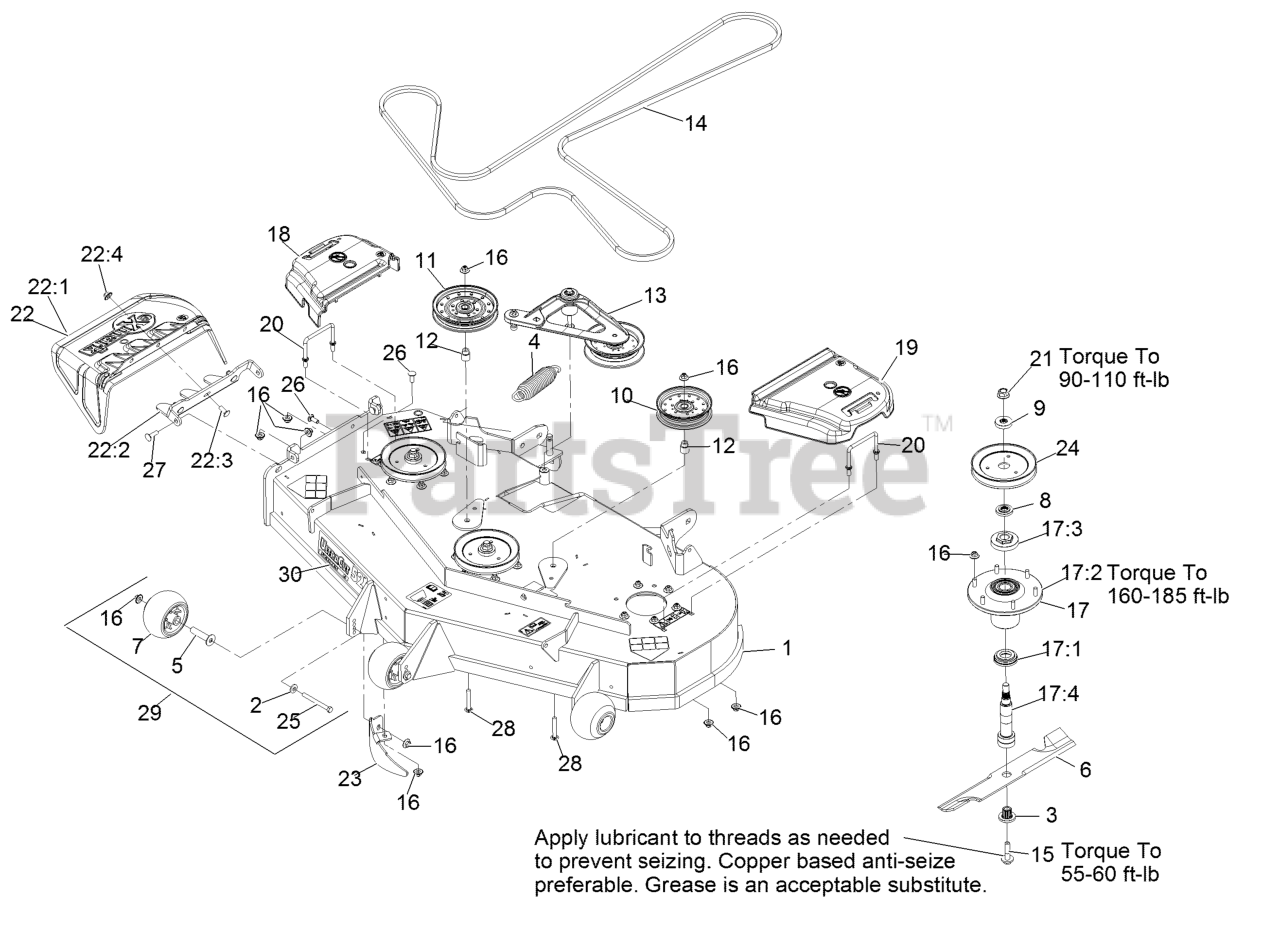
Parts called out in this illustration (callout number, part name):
1	ASM,DECK W/ DECALS 52
2	WASHER-BELLEVILLE
3	BUSHING,SPLINED
4	SPRING-EXTENSION
5	AXLE, ROLLER
7	ROLLER-SCALP, ANTI
8	SPACER,SPLINED STEPPED
9	SPACER,SPLINED
12	BUSHING-IDLER
13	DECK IDLER ASM
14	BELT,V-B X 186.00"
15	SCREW,SEMS 1/2-20 X 2.19
16	Nut-Nyloc 3/8-16 Flg
17	ASM,SPINDLE HOUSING
17:1	GUARD,BOTTOM
17:2	ASM,CUTTER HOUSING
17:3	NUT, SPINDLE 7/8-14
17:4	SPINDLE,DOUBLE SPLINE
18	COVER-BELT, RH
19	COVER-BELT, LH
20	WIREFORM-COVER
21	NUT-FLANGE, CENTERLOCK
22	ASM,DISCHARGE CHUTE
22:1	CHUTE,DISCHARGE
22:2	BRACKET,DISCHARGE CHUTE
22:3	SCREW-CARR
22:4	Nut-Nyloc 3/8-16 Flg
23	BAFFLE-DOGLEG, LZ-VT52
24	SHEAVE,BLADE DRIVE
25	SCREW-HH 3/8-16 X 3 3/4 GR 8
26	SCREW-CARR
27	Bolt-Carriage 3/8-16 X 1 1/4
28	SCREW-CARR
29	KIT, ANTI-SCALP ROLLER
30	DECAL,ULTRACUT 52 SERIES
